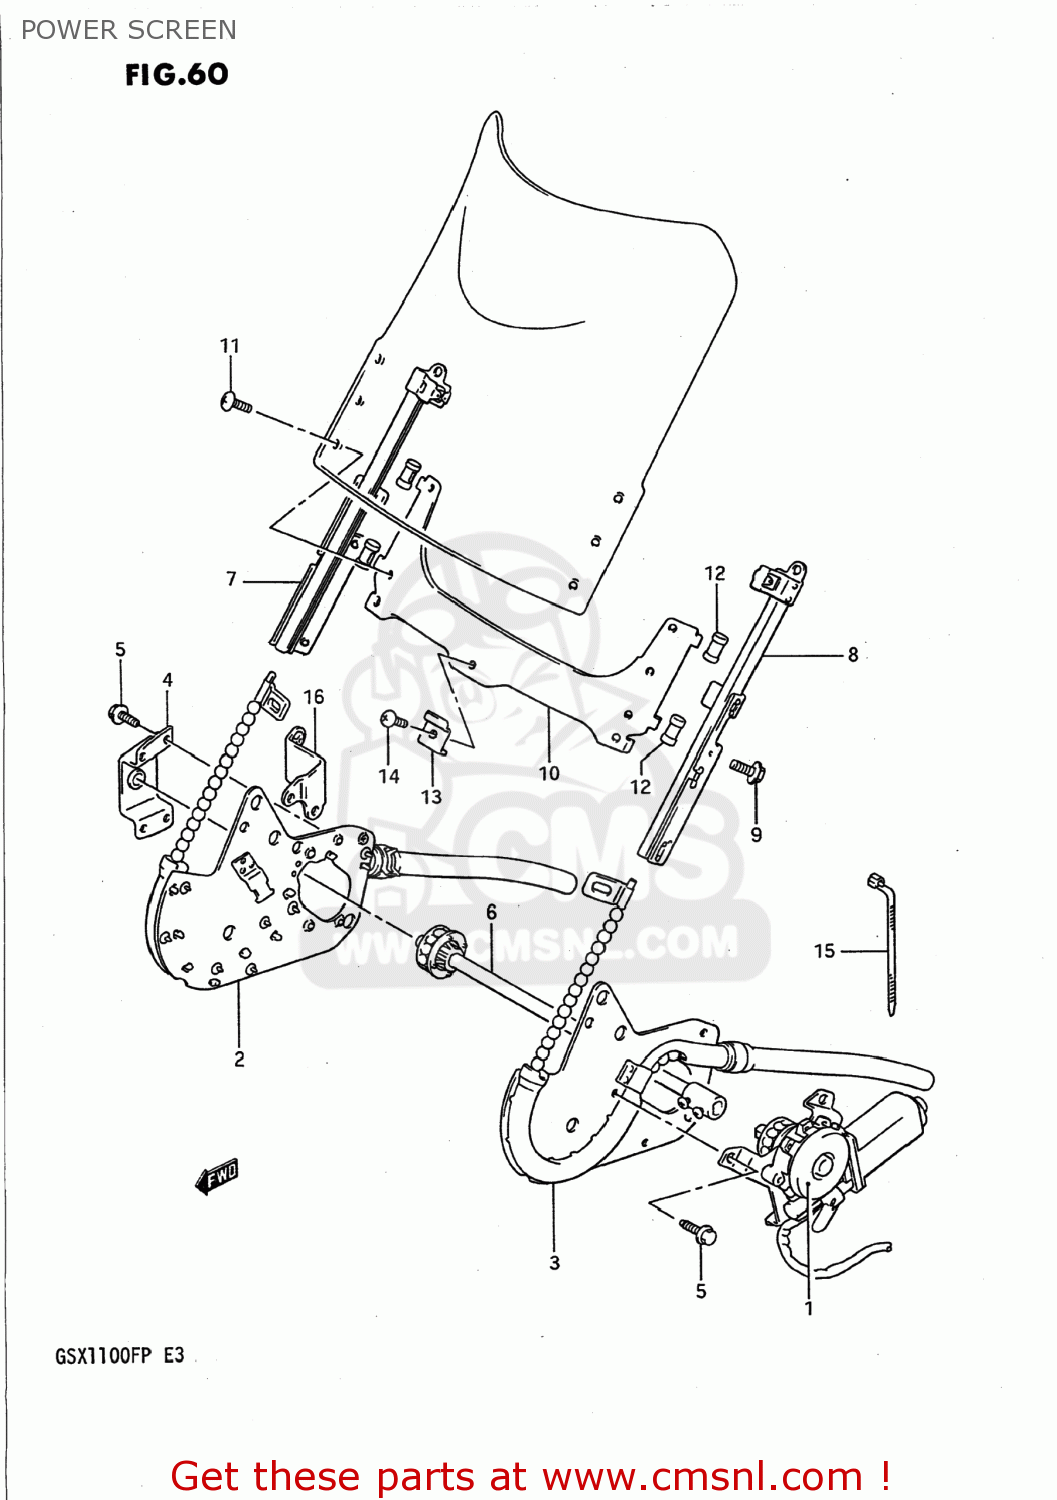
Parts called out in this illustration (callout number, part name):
1	MOTOR SET
2	FRAME SET,RIGHT
3	FRAME SET,L
4	METAL BRACKET SET
5	BOLT
6	SHAFT SET
7	PIPE SET,GUIDE,R
8	PIPE SET,GUIDE,L
9	BOLT
10	BRACKET,SCREEN
11	SCREW, FRONT & REAR
12	RUBBER,SLIDE
13	BRACKET,SUPPORT
14	SCREW
15	CLAMP
16	BRACKET
